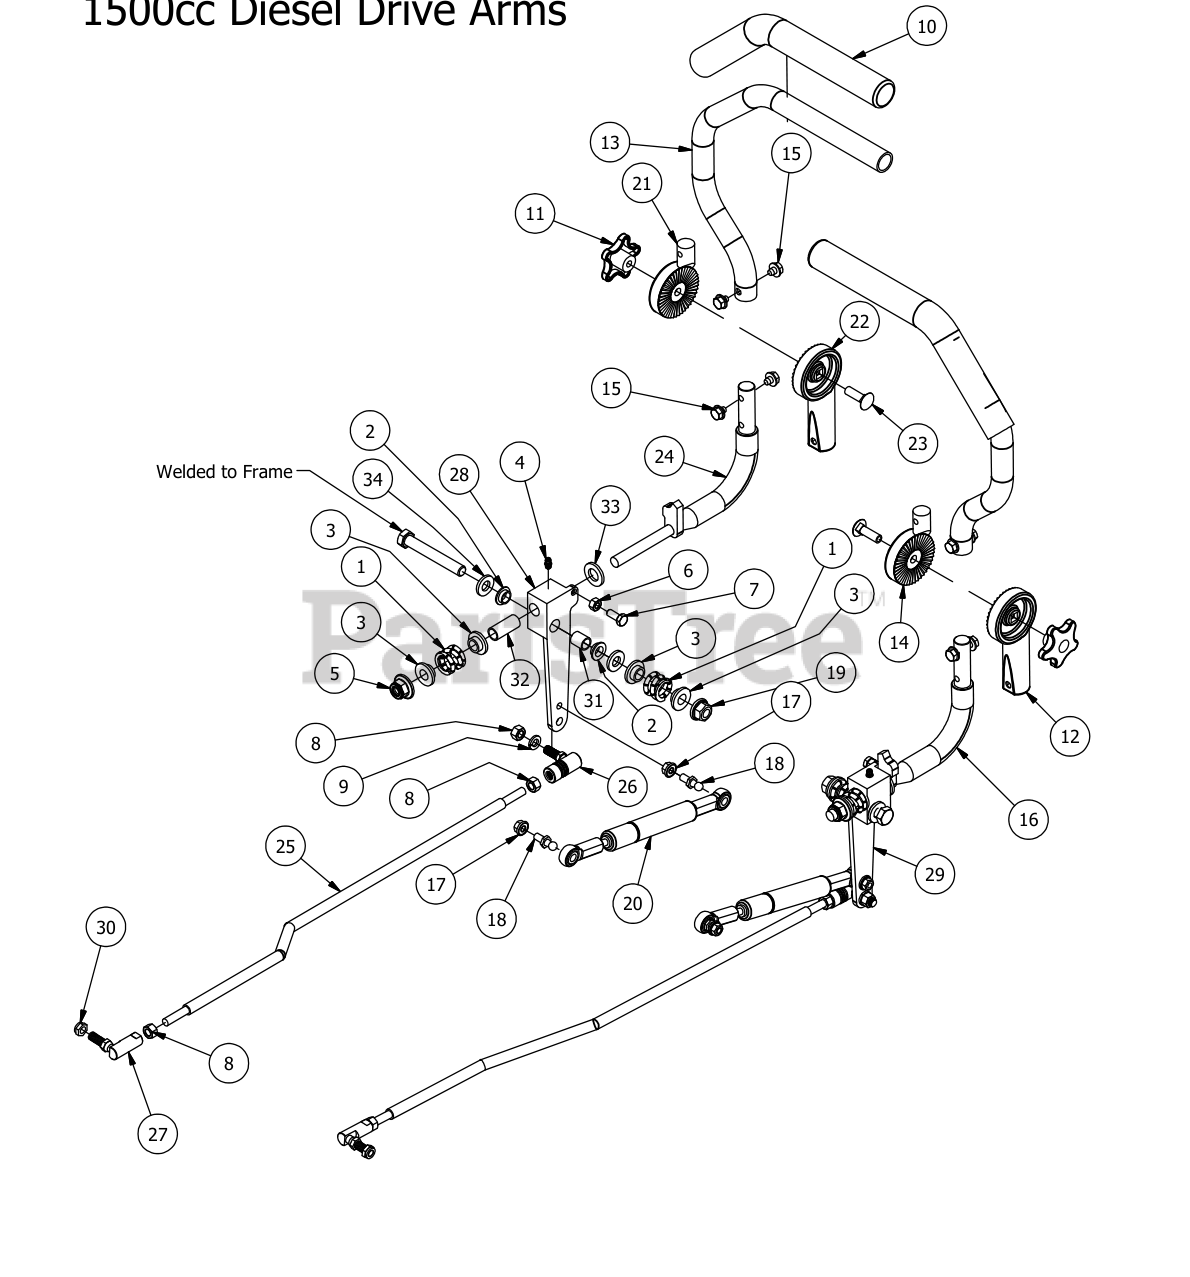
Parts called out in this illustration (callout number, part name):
1	Drive Lever Spring
2	Bushing for 2012 Drive Arms
3	.515 ID Nylon Shoulder Washer
4	1/4" Press in Grease Fitting
5	1/2-13 Nylon Flange Nut
7	5/16" x 3/4" Hex Bolt
8	3/8" Fine Threaded Jam Nut
9	3/8" Lock Washer
10	Black Steering Grip
11	Black Knob for Adjustable Steering Arm
12	Lower Adjuster - Steering Arm- Right
13	Upper Tube-Adjustable Steering
14	Upper Adjust Steering Arm- Right
15	5/16-18 1/2 HWH Bolt-Steering
16	Steering Arm Elbow - Right
17	5/16" Flange Nut
18	10mm Damper Ball Stud-Steering
19	1/2-13 Mechanical Lock Nut Grade F
20	Steering Damper
21	Upper adjuster-Steering Arm- Left
22	Lower Adjuster - Steering Arm- Left
23	3/8" x 1 1/4" Carriage Bolt
24	Steering Arm Elbow - Left
25	1500cc Diesel Push Rod
26	Quick Release Ball Joint
27	3/8-24 Ball Joint
28	Drive Arm Lever Housing (Left)
29	Drive Arm Lever Housing Right
30	3/8-24 Nylon Insert jam locknut
31	Drive Arm Block Insert-short
32	Drive Arm Block Insert-long
33	.630 ID Plastic Washer
34	.505x1x.125 Oil Impregnated washer
